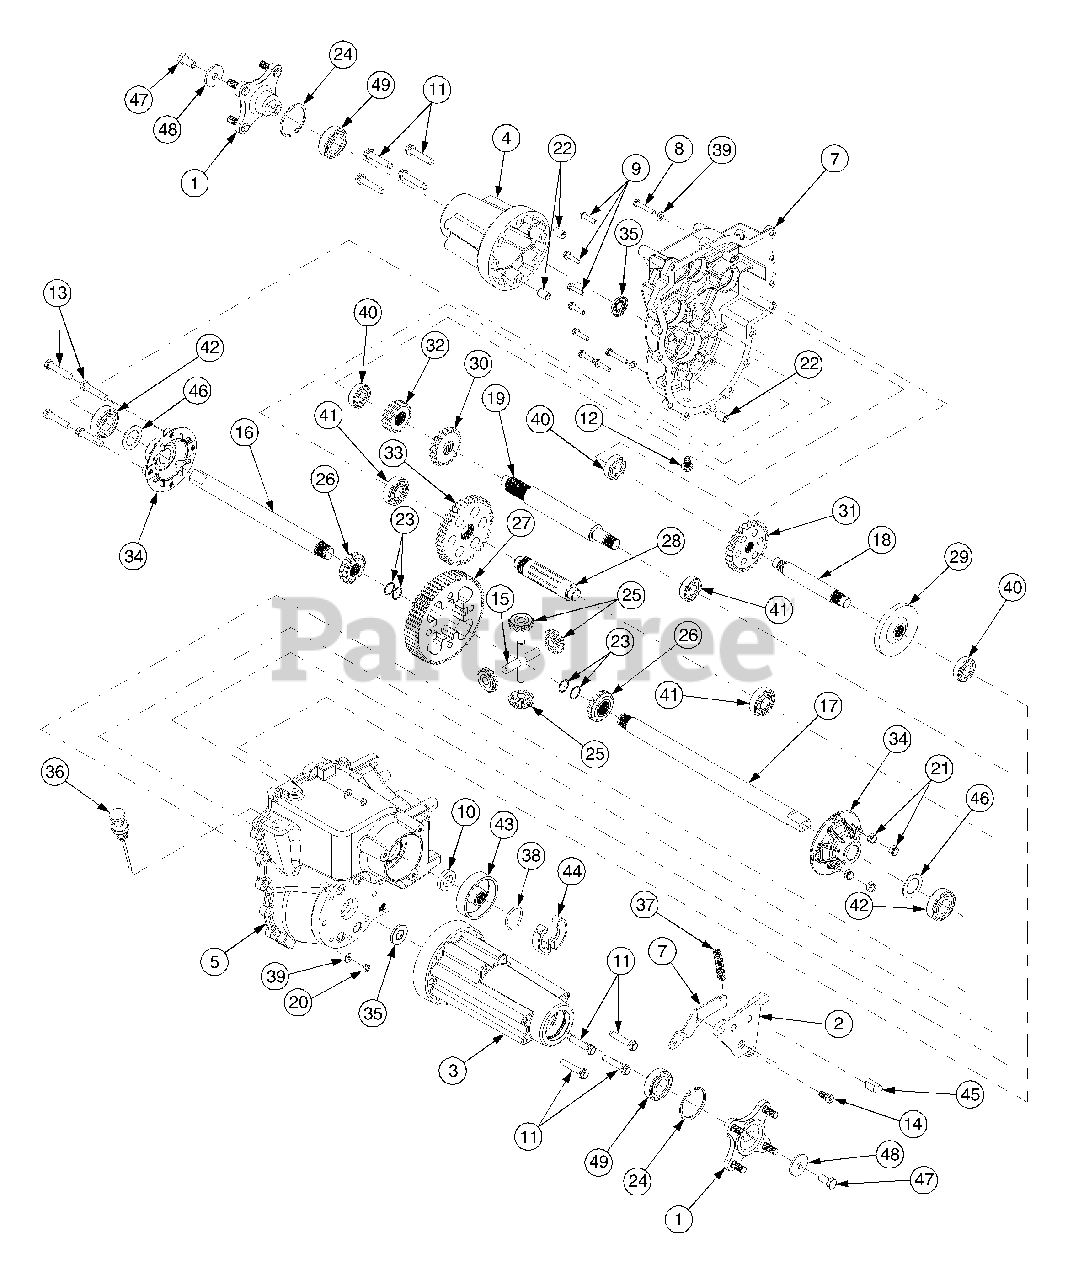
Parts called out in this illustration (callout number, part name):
1	Hub Assembly, Wheel
2	Plate Assembly, Brake
3	Axle Housing, RH
4	Axle Housing, LH
5	Transmission Housing, RH
6	Transmission Housing, LH
7	Brake Arm
8	Screw, Hex Cap, 1/4-20 x 1.5
9	Screw, Hex Wash Hd Tap, 1/4-20 x 1.0
10	Seal, Shift Shaft
11	Screw, TT, 3/8-16 x 1.875
12	Screw, Plug, M14 x 1.5 x .827
13	Screw, Hex Cap, 3/8-16 x 2.0 GR5
14	Screw, Cap, 3/8-16 x .750
15	Shaft, Cross, .500 x 3.005
16	Shaft, Axle, 1.00 x 12.07
17	Shaft, Axle, 1.00 x 15.73
18	Shaft, Drive
19	Shaft, Intermediate
20	Nut, Hex Center Lock, 1/4-20
21	Nut, Hex Insert Lock, 3/8-16 GR5
22	Dowel Bushing
23	Ring, Retaining, .938
24	Ring, Retaining,
25	Gear, Miter, 10T
26	Gear, Miter, 14T
27	Gear, Differential Spur, 60T
28	Shaft, Output, 9T
29	Gear, Bevel, 36T
30	Gear, Spur, 18T
31	Gear, Spur, 27T
32	Gear, Spur, 16T
33	Gear, Spur, 42T
34	Housing, Differential, RH
35	Seal, Oil, 1.0 x 1.499
36	Dipsick, Oil
37	Spring, Compression
38	Spring, Brake Shoe
39	Washer, Flat, .25 x .630 x .0515
40	Bearing, Ball, 17 ID x 40 OD x 12
41	Bearing, Ball, 6204
42	Bearing, Ball, 6205-1
43	Drum, Brake
44	Brake, Shoe
45	Brake, Actuator
46	Washer, Flat, 1.010 x .56 x .060
47	Screw, Hex Lock, 3/8-16 x .75 GR5
48	Washer, Flat, .39 x 1.5 x 1.34
49	Bearing, Ball
